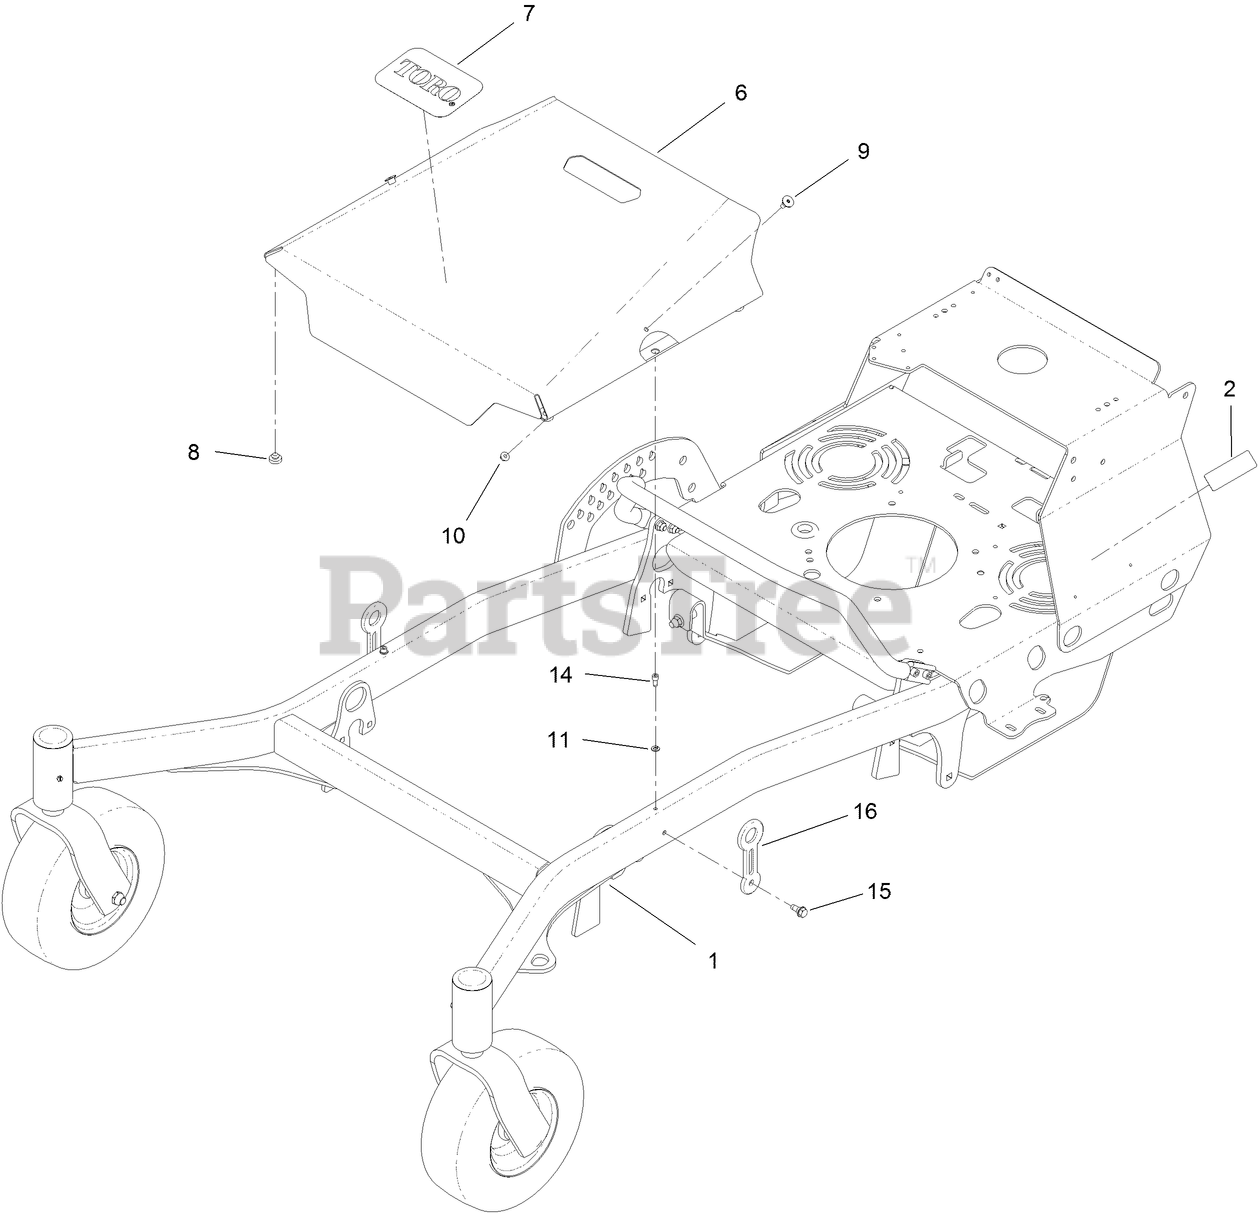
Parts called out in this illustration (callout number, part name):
1	FRAME ASSEMBLY
2	DECAL-EMISSIONS, EPA 2020
6	COVER-DECK,WIDE
7	DECAL
8	BUMPER
10	NUT-HF
11	WASHER-LOCK
14	SCREW-HSH, THREAD FORMING
15	SCREW-SHOULDER
16	LATCH-RUBBER
